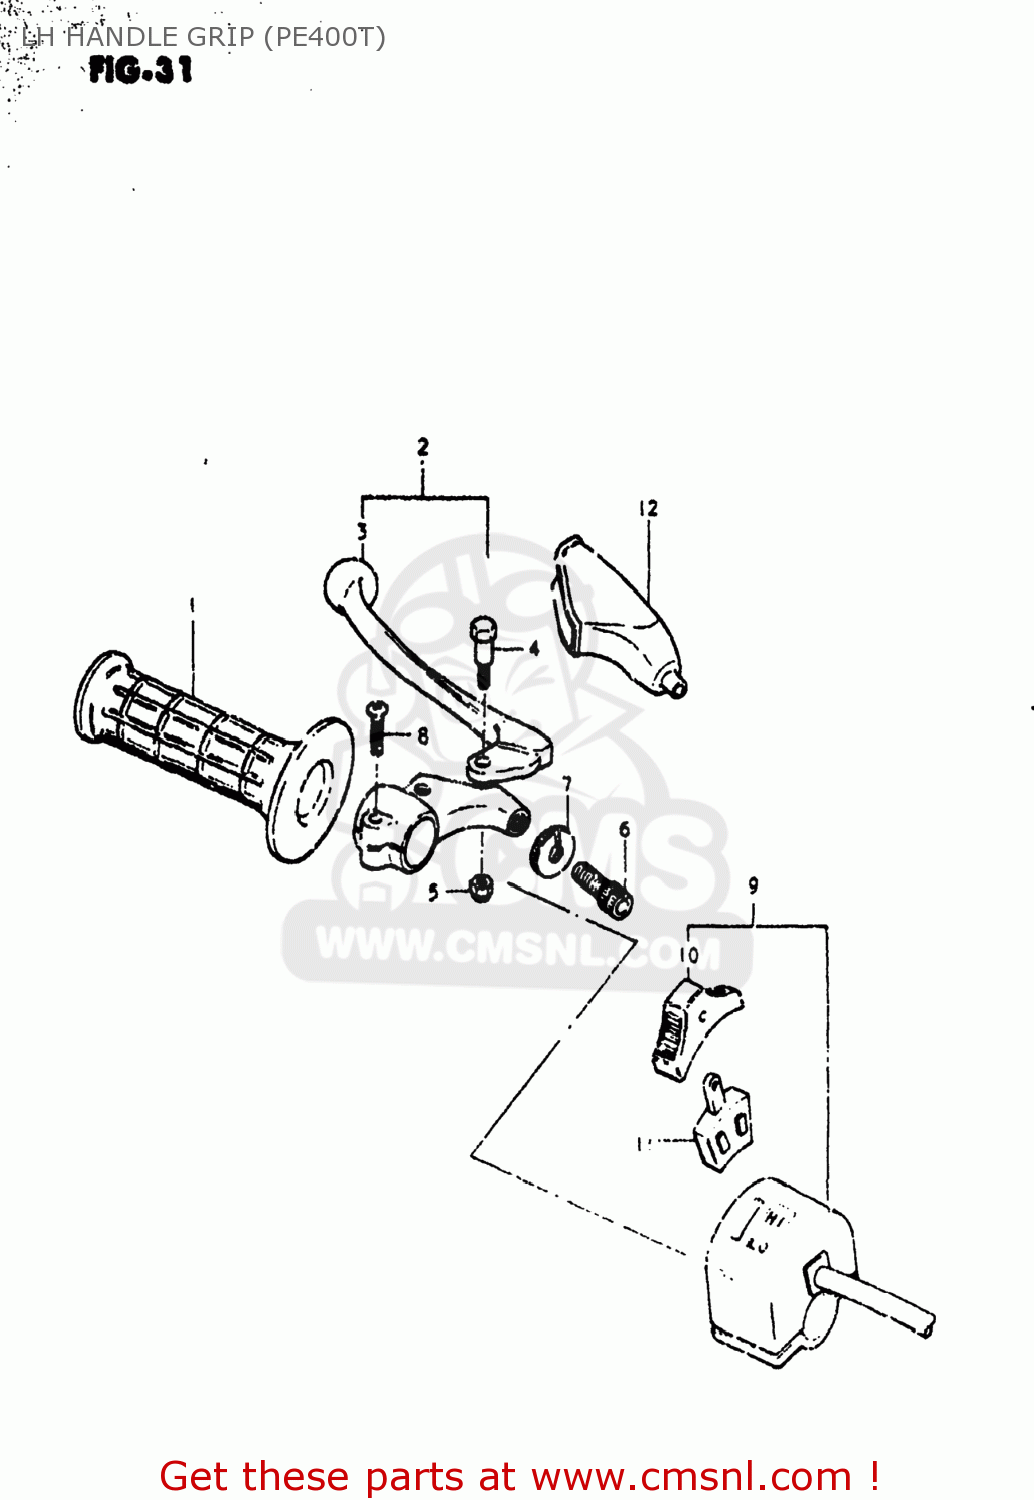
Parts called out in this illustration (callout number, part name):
1	GRIP,LEFT
2	LEVER ASSY,CLUTCH
3	LEVER,CLUTCH
4	BOLT,LEVER
5	NUT 6MM
6	ADJUSTER,CABLE
7	NUT,CABLE ADJUSTER
8	SCREW
9	SWITCH,DIMMER
10	KNOB,LIGHTING & DIMMER
11	BLOCK,LIGHTING/DIMMER
12	COVER,CLUTCH LEVER
